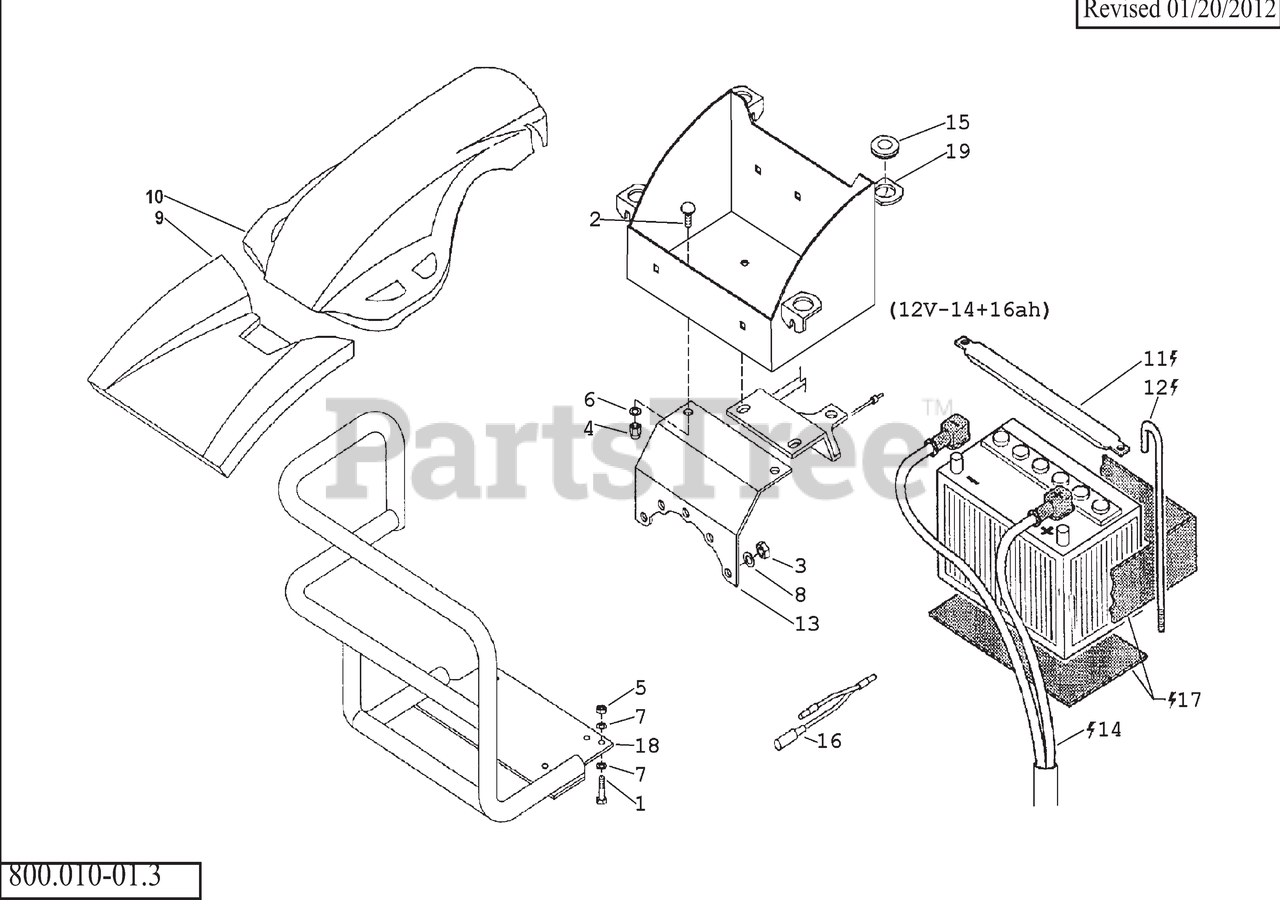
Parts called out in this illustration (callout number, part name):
1	CAP SCREW, M8X40
2	BOLT, M6 X 16
3	NUT M8
4	NUT, LOCK, M6
5	NUT, LOCK, M8
6	WASHER, FLAT, M6
7	WASHER, FLAT, M8
8	WASHER, LOCK, M8.4
9	GUARD, LOWER
10	GUARD, STEERING COLUMN
11	BATTERY BRACKET
13	SUPPORT, BATTERY/ TOOL BOX
14	CABLE, ELECTRIC STARTER
15	SUPPORT, BODY GUARD
16	WIRE HARNESS
17	PAD SET, ANTI SHOCK
18	BUMPER, GX390
19A	BATTERY / TOOL BOX
19B	SUPPORT, LOWER GAURD (NOT
